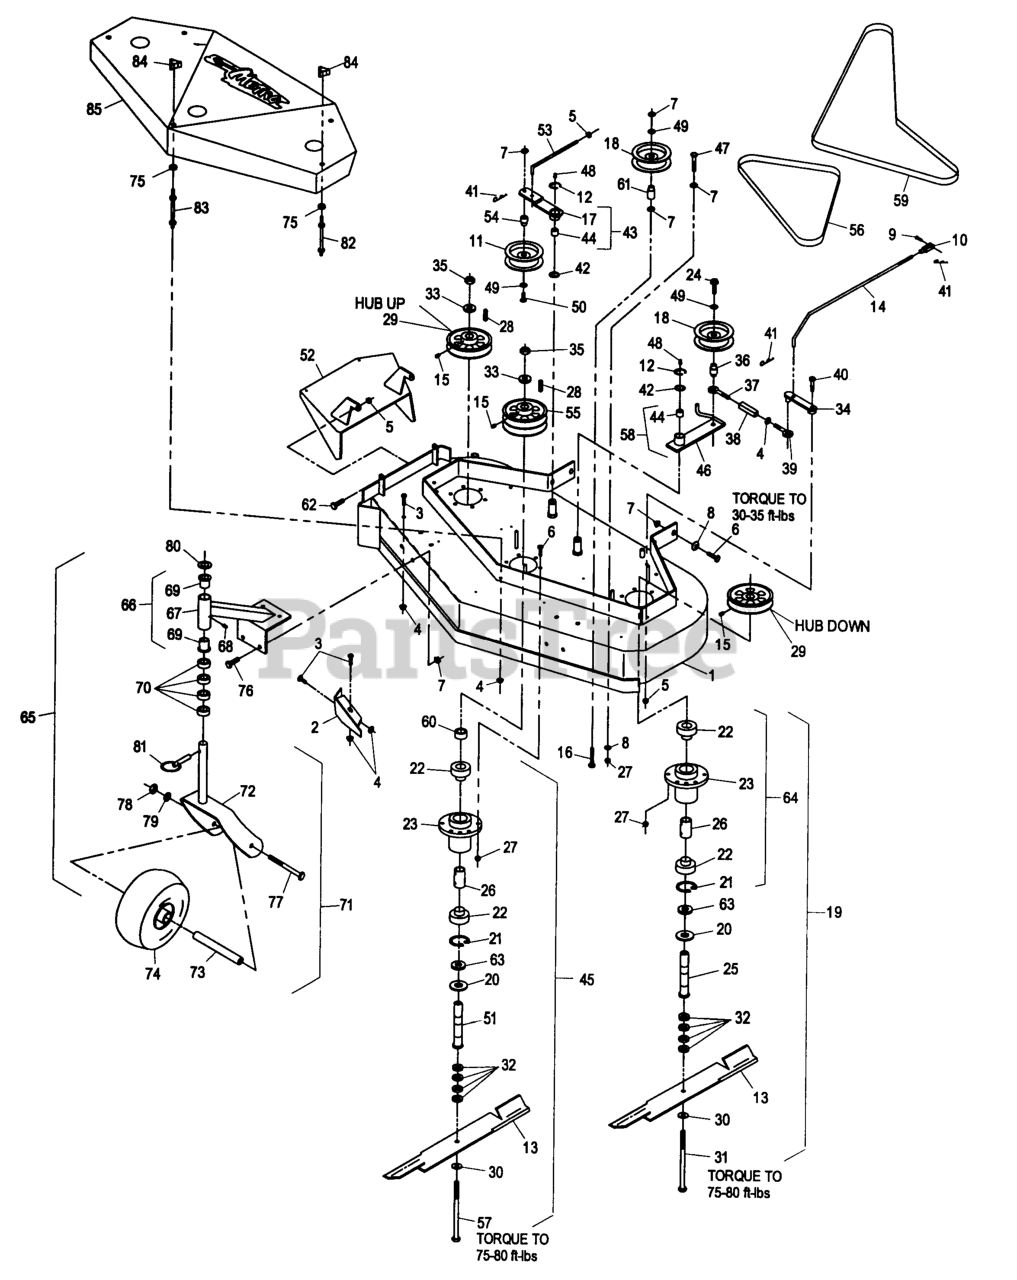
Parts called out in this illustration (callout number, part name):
2	BAFFLE-DOGLEG
9	PIN-CLEVIS
10	YOKE-ADJUSTABLE
11	IDLER,PULLEY
14	ARM-ASSIST, LINKAGE
15	SCREW-SET
16	BOLT,TAP HH3/8-16X2-1/4
17	Arm Weldmt, Rh
19	HOUSING,CUTTER COMPLETE(S
20	GUARD-BEARING, BOTTOM
22	BEARING
25	TUBE-SPINDLE, SHORT
26	SPACER-BEARING
30	WASHER-SPRING
31	SCREW-CAP, HH
33	WASHER-RETAINER, SHEAVE
36	BUSHING-ENGAGEMENT
37	EYEBOLT-THREAD, LH
38	BODY-TURNBUCKLE
39	EYEBOLT-THREAD, RH
40	BOLT,SHLDR KSKH
41	PIN-COTTER
42	WASHER-SPINDLE
43	ARM WLDMNT W/BUSHING
44	BEARING,POWDERED METAL
45	HOUSING,CUTTER COMPLETE(S
51	TUBE,SPINDLE LONG
53	LINKAGE
54	BUSHING-IDLER
56	BELT,FRONT DECK
57	SCRW,CAP HH 5/8-18X8.5
59	BELT,BLADE DRIVE
60	SPACER,SHEAVE/BEARING
61	BUSHING,IDLER
63	SPACER-PULLEY/BEARING
65	CASTER/MOUNT ASM
66	SUPPORT ASM
69	BEARING-FLANGED
70	SPACER-CASTER
80	WASHER-FLAT
82	STUD-SHIELD, BELT (SHORT)
83	STUD-SHIELD, BELT (LONG)
84	KNOB-3 PRONG
